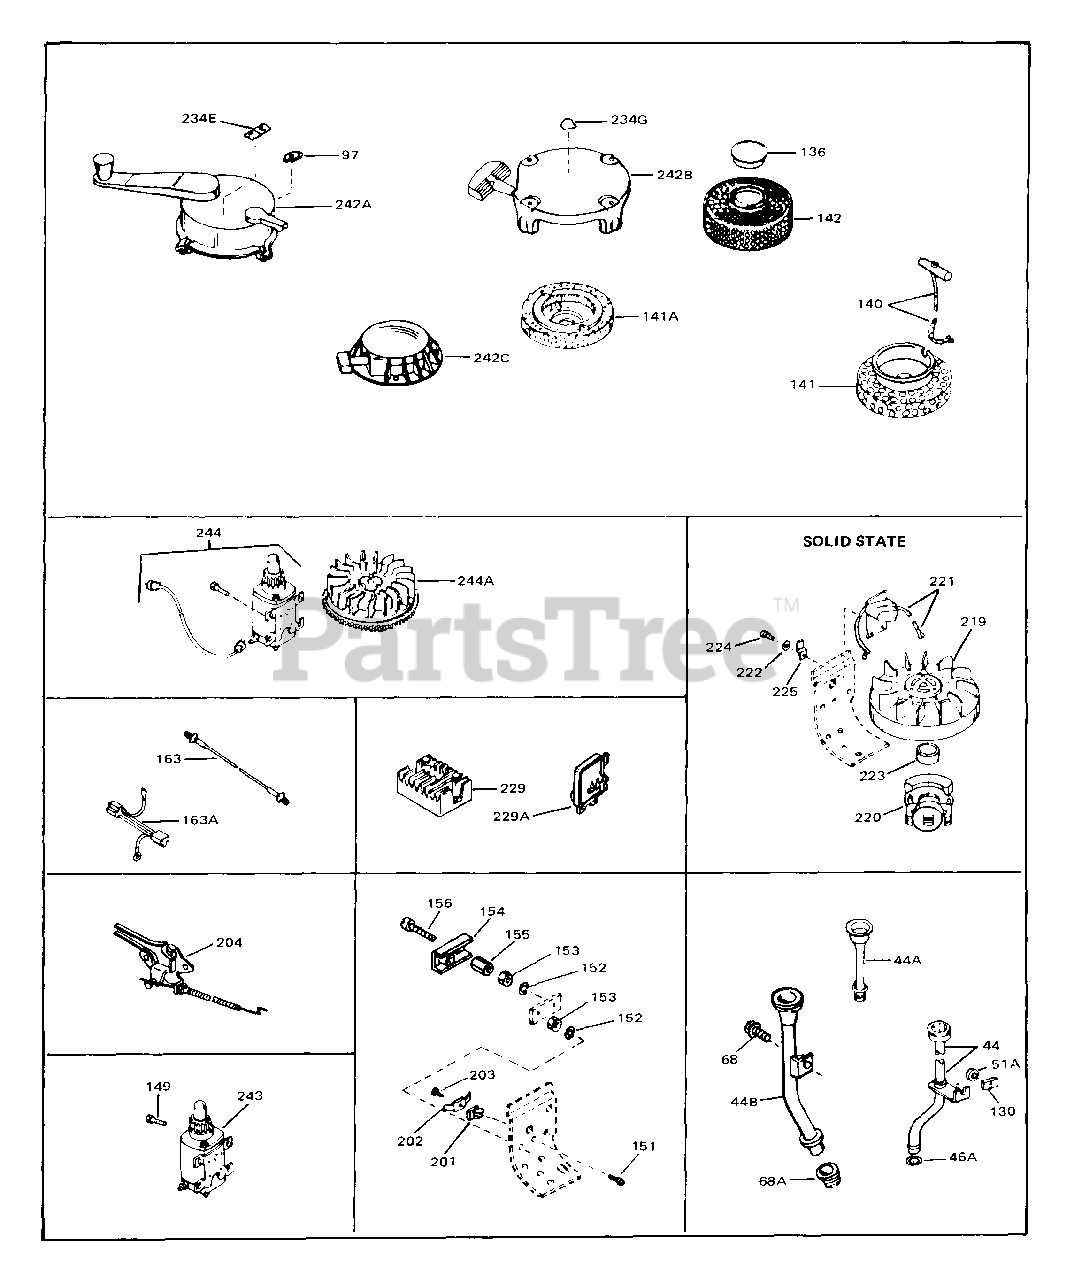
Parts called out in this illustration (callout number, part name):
51A	Washer, Flat
51A	Washer, Belleville
97	Clip, Retaining
130	Plate, Securing
140	Rope & Handle Assy., Starter
141	Pulley, Starter
149	Screw, Hex hd. Sems, 1/4-20 x 1/2
151	Screw, Phil. rd. hd., 5-40 x 9/16
152	Lockwasher
154	Cover, Rectifier panel
155	Nut, Long 5-40
163A	Harness, Adapter
164	Screen, Muffler
201	Grommet, Plastic
202	Terminal, Ground
203	Screw
204	Control, Throttle
234G	Decal, Ezee-start
244	Starter Motor Kit (110-120 Volt)
244A	Flywheel
